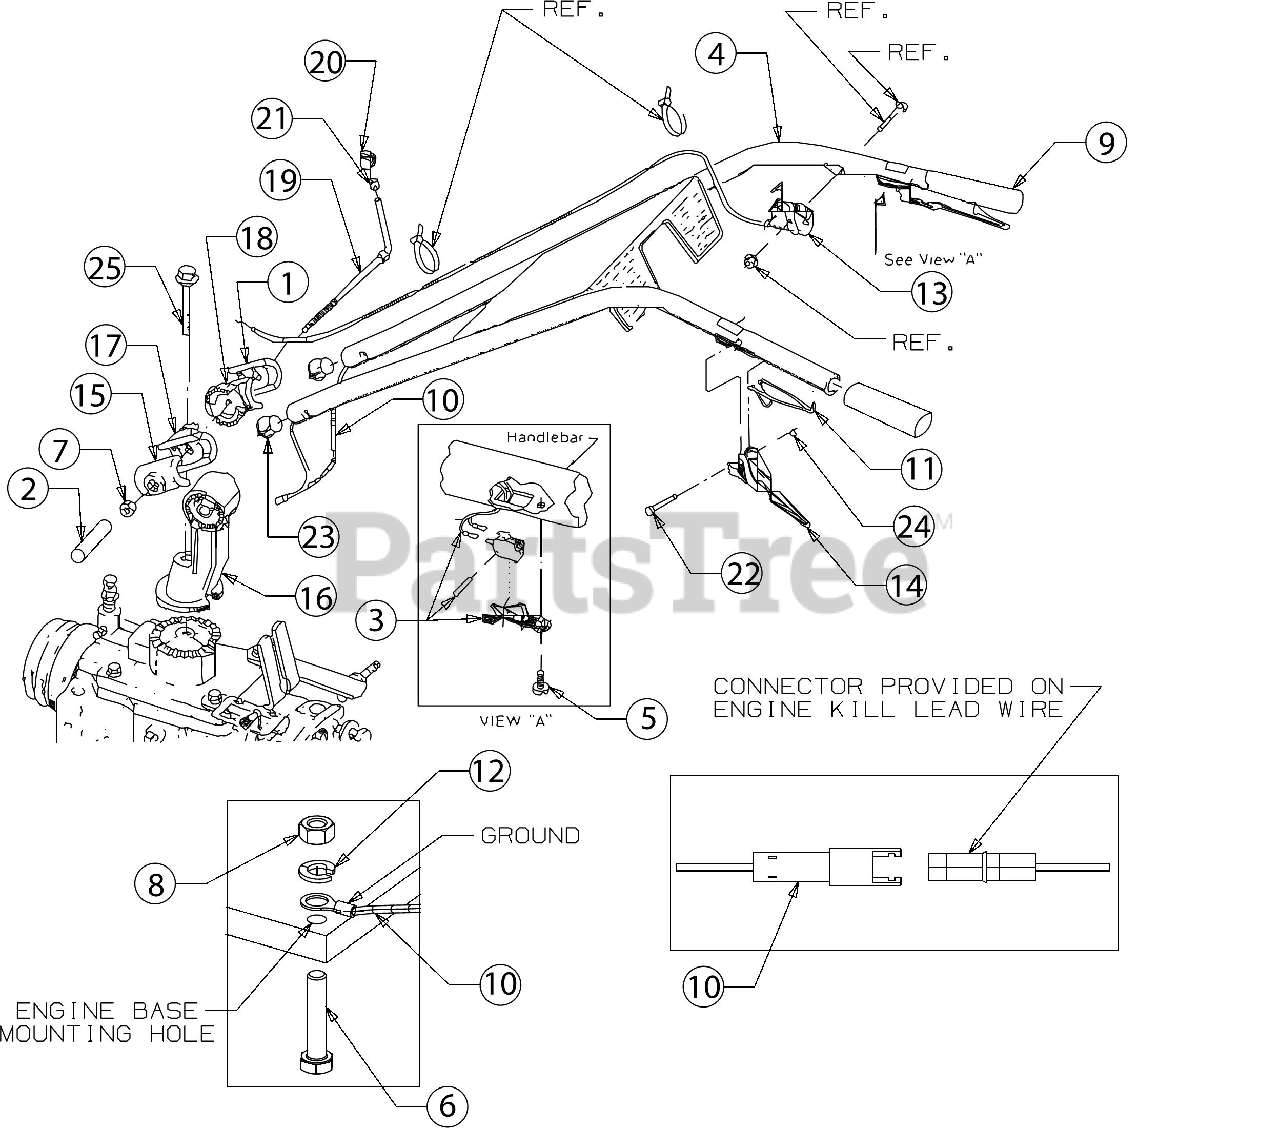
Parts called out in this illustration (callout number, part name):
1	CLAMP (RH) HORSE
2	CAP:PLUG HI TEMP
3	MICRO SWITCH ASSEMBLY
3	MICRO SWITCH
4	HANDLE ASSEMBLY
5	SCREW #10-16 X .500
6	SCREW 5/16-18 X 1.5 LG
7	HEX NUT
8	HEX NUT
9	GRIP 1.188 X 4.562
10	ENGINE HARNESS
12	LOCK WASHER 5/16
13	THROTTLE CABLE ASSEMBLY
15	CLAMP (LH) HORSE
16	HANDLE BAR BAS
17	RATCHET (LH) RED
18	RATCHET (RH) RED
19	STUD-H/BAR W/NUT
20	CONTROL KNOB
21	RING-TOLERANCE
22	PIN-PIVOT
23	RETAINER-HARNESS
24	RING-KLIP
25	BOLT 132-13X3.5 FH
